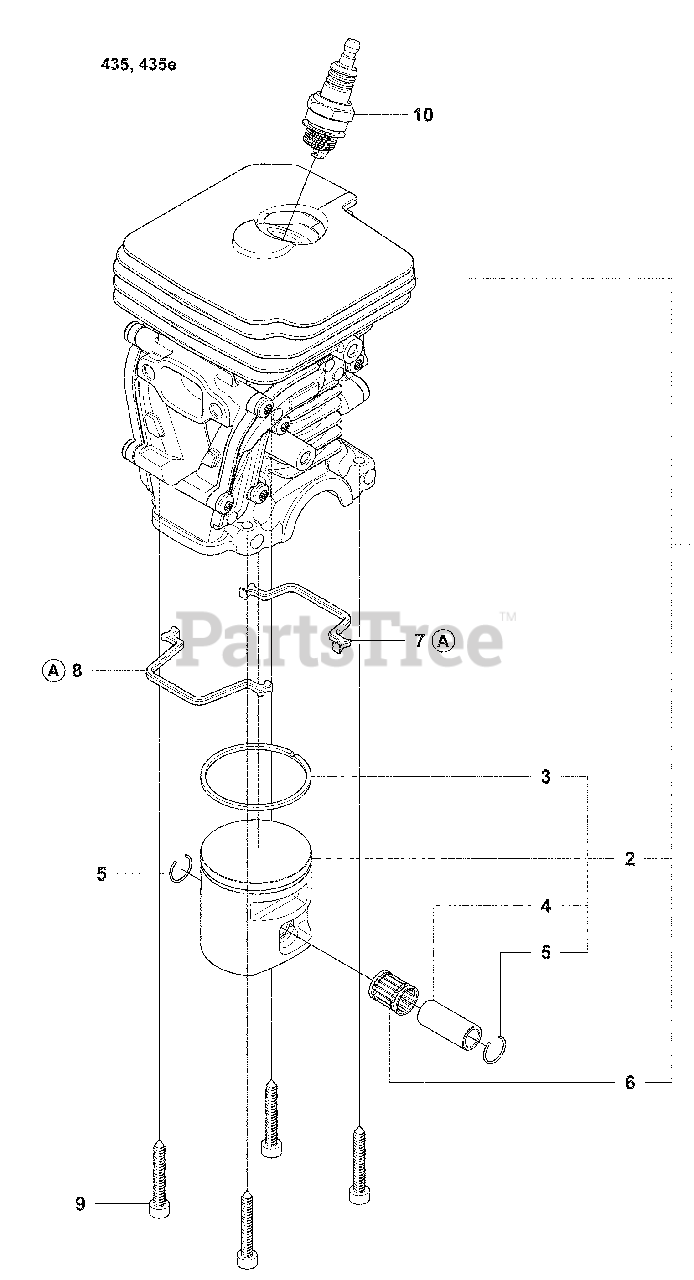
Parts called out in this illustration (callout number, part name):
1	Cylinder Assembly
2	Piston Assembly, 37cc
3	Piston Ring
4	Piston Pin
5	Locking Ring
6	Support Bushing
7	Cylinder Gasket, Rear
8	Cylinder Gasket, Front
9	Screw, MC6S 5 X 25
10	Solid Spark Plug, BPMR7A
